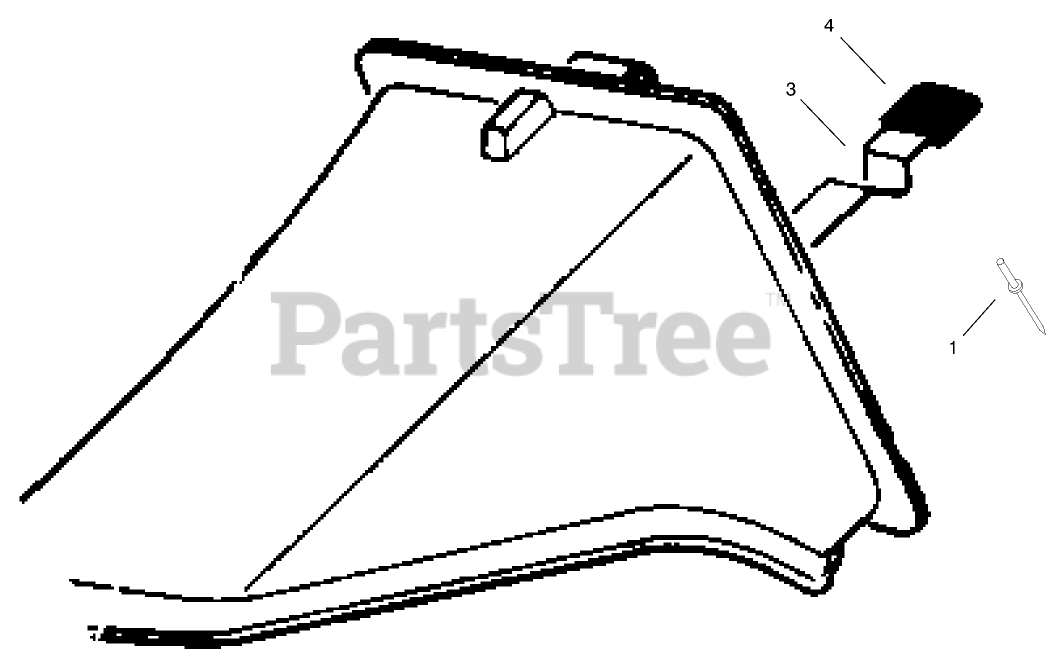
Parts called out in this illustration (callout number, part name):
1	RIVET-HEAD, FLAT
3	LATCH-PLUG, DISCHARGE
4	GRIP-LATCH
